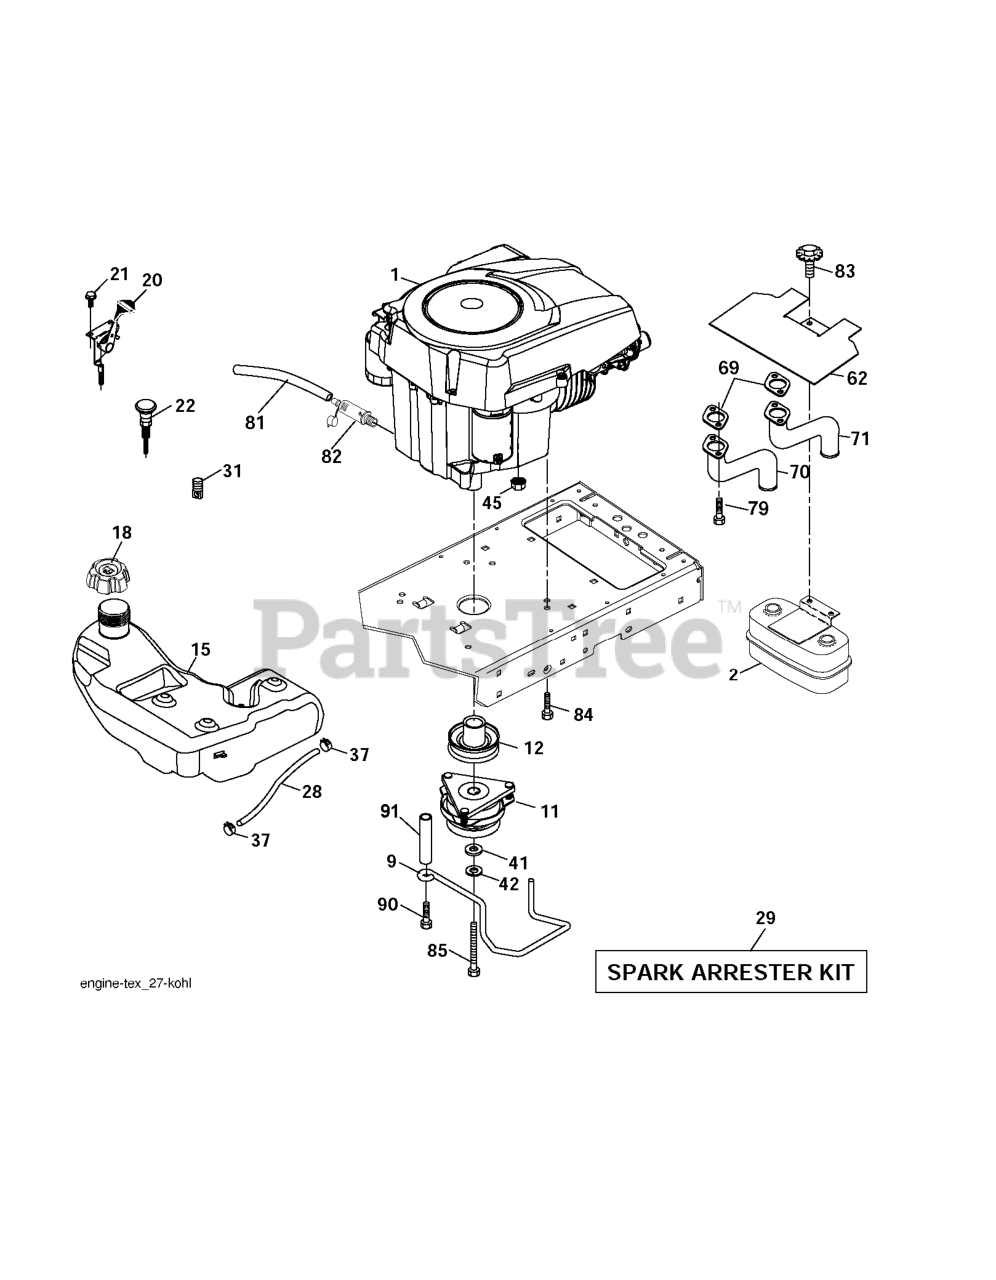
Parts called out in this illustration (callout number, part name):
2	MUFFLER.TWIN.CYL.LOW.TONE
9	KEEPER.BELT.ENGINE.4.2
11	CLUTCH MZ ZTR GT.48/54"1.125"
12	PULLEY ENGINE
15	TANK.FUEL.4GAL
18	CAP.FUEL.TANK.3"GREY
20	THROTTLE CONTROL
21	SCREW
22	CONTROL.CHOKE.ERGO.PUSH-IN.BLA
28	FUEL LINE 54"
29	KIT.SPARK ARRESTOR 794945 B&S
37	HOSE CLAMP
42	LOCKWASHER
45	NUT
62	RP SHIELD HEAT MUFFLER
69	GASKET.EXHAUST.KOHL.CV18-CV26
70	RP.PIPE-EXHAUST LH
71	RP.PIPE-EXHAUST RH
79	SCREW.SOCKET HD.5/16-1
81	TUBE, DRAIN OIL ASM.
82	PLUG DRAIN OIL EASY
83	BOLT.5/16-18UNCX1.W/SEMS.BLK
84	SCREW 3/8-16X1
85	BOLT HEX 7/16-20 X 3.75 GR. 5
90	SCREW 3/8-16X1
91	BUSHING.1.375OD
